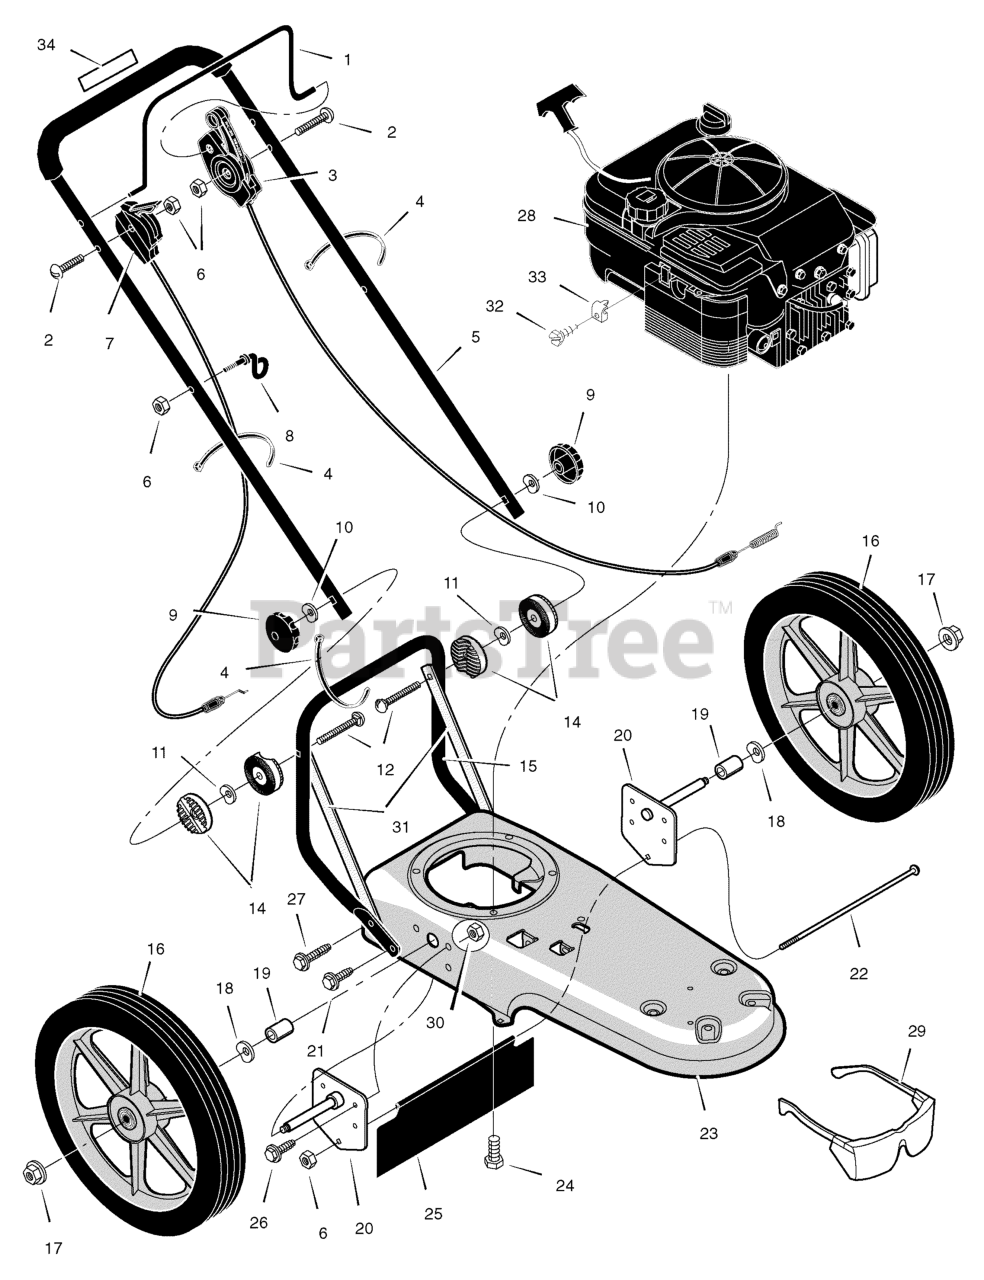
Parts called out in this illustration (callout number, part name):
1	Lever, Stop
3	Cable, Control Latching
4	Tie, Cable
6	Nut
7	Control, Throttle
8	Guide, Rope
9	Knob, Handle
11	Washer, Spring
14	Pivot, Handle
15	Handle, Lower
16	Wheel & Tire
17	Nut, Axle
18	Washer, Spring
20	Assembly, Axle & Bracket
22	Bolt, Carriage
23	Frame, Trimmer
25	Shield, Trailing
26	Bolt
28	Engine
29	Protection, Eye
30	Nut
31	Strap, Vibration Trim
33	Clamp, Throttle
34	Decal, CE Handle
